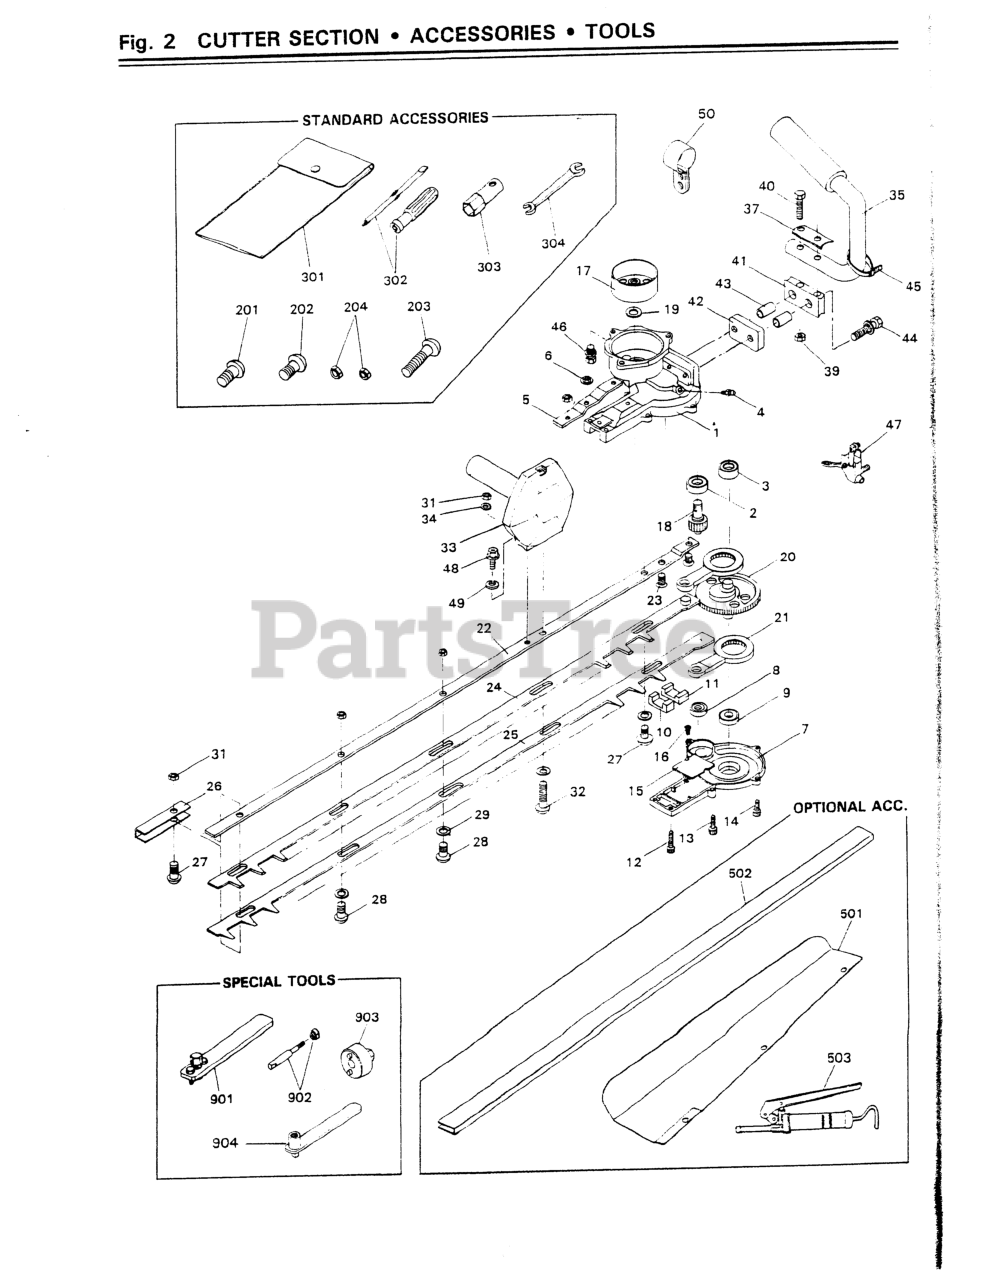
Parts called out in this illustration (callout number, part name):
1	CASE, MIDDLE
2	BEARING
3	BEARING (NLA)
4	FITTING, GREASE
5	PLATE (USE 3876-11670)
6	NUT
8	BEARING (RPLS. T4001-31340)
9	BEARING (NLA)
10	FELT (A)
11	FELT (B)
12	BOLT, M5 X 22
14	BOLT, M5 X 16
15	PLATE
16	SCREW, M3 x 6
19	DRUM COLLAR
21	ROD ASSEMBLY (NLA)
23	BOLT, M5 x 20
24	BLADE, UPPER, 30
25	BLADE, LOWER, 30
26	REINFORCE, END
28	SCREW (USE 3884-11750-10)
29	WASHER (RPLS 3873-11760)
31	NUT, M6
34	WASHER, M6 x .8
37	PLATE, BACK
40	BOLT, M5 x 45
42	ABSORBER
44	BOLT, M6x35 (RPLS -50635)
45	BAND, CABLE
46	BOLT, M6 X 14
47	LEVER ASSEMBLY
48	BOLT
201	SCREW (USE 3884-11750-10)
204	NUT, M6
302	SCREWDRIVER
303	SOCKET, HEX, 3/4
502	COVER, BLADE (30
503	PUMP, GREASE
902	(H) ROD ASSY
903	WRENCH (TOOL)
NI	TOOL SET
